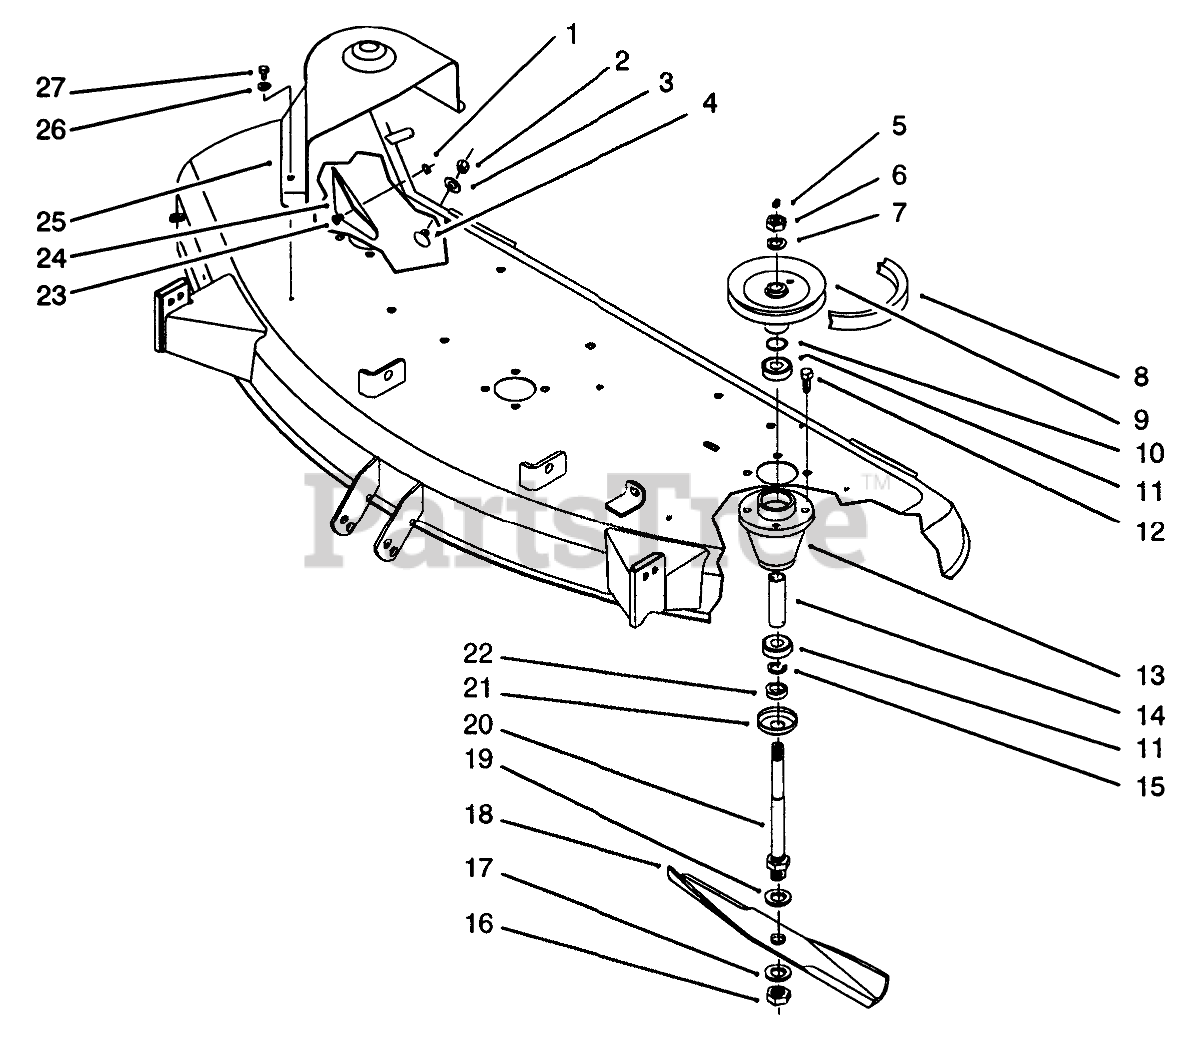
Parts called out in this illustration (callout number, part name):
1	NUT-LOCK, NI
2	NUT-LOCK, NI
3	WASHER-FLAT
4	SCREW-CARR
5	FITTING-GREASE
6	NUT-JAM
7	WASHER-LOCK
8	Belt-V
9	Pulley-Spindle
10	O RING
11	BEARING-BALL
12	SCREW-HH
13	HOUSING-SPINDLE
15	RING-RETAINING
16	NUT-JAM
17	WASHER-FLAT
18	BLADE KIT (3 PACK)
19	Washer
20	SHAFT-SPINDLE
21	CUP-SPINDLE
22	SPACER-BLADE
23	SCREW-HH
24	Guard-Chute
25	COVER-BELT, RH
26	WASHER-FLAT
27	Bolt
